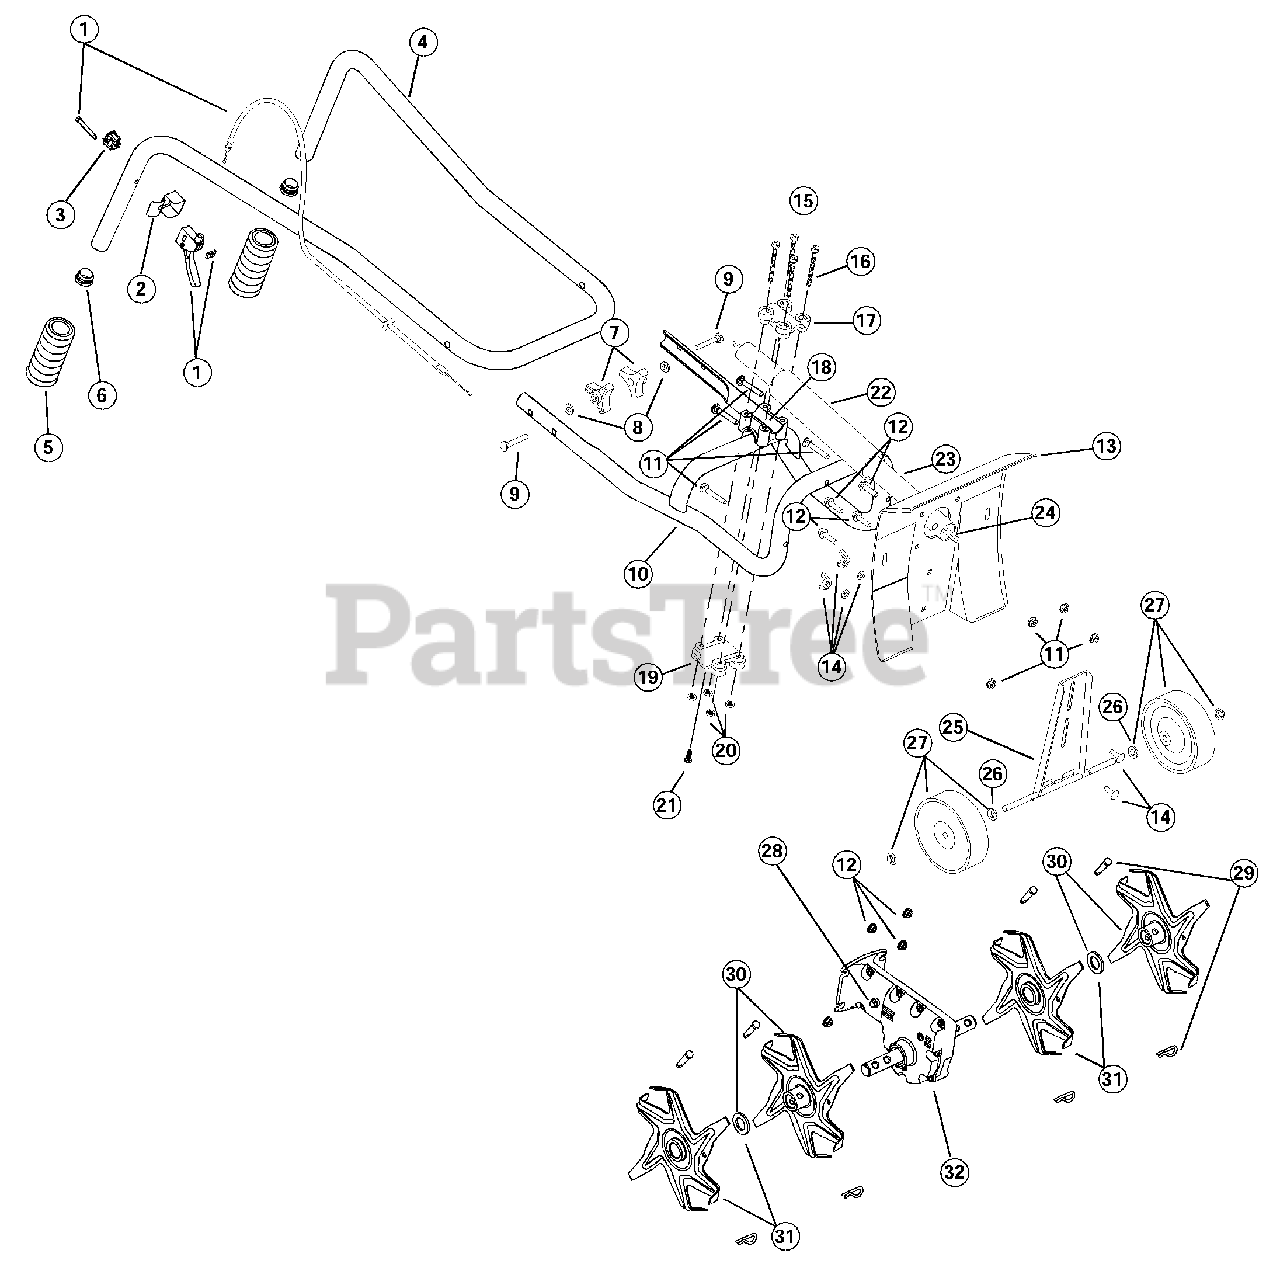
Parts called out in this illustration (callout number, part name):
1	Throttle Trigger and Cable Assembly
2	Switch Bracket
3	Ignition Switch
4	Upper Handlebar Assembly
6	Tube Closure
7	Handlebar Knob
8	Washer
10	Lower Handlebar Assembly
11	Handlebar Mounting Hardware
12	Gearbox Mounting Hardware
14	Wheel Bracket Mounting Hardware
15	Handle Bracket Assembly
17	Upper Handle Clamp
18	Middle Handle Clamp
19	Lower Handle Clamp
21	Anti-Rotation Screw
23	Drive Shaft Housing Assembly
24	Flexible Drive Shaft
25	Wheel Bracket Assembly
26	Wheel Spacer
27	Wheel Assembly
28	Sleeve Retainer Bolt
29	Tine Fastener Assembly
30	Tine Assembly (Left Outer or Right Inner)
31	Tine Assembly (Left Inner or Right Outer)
32	Gear Box Assembly
